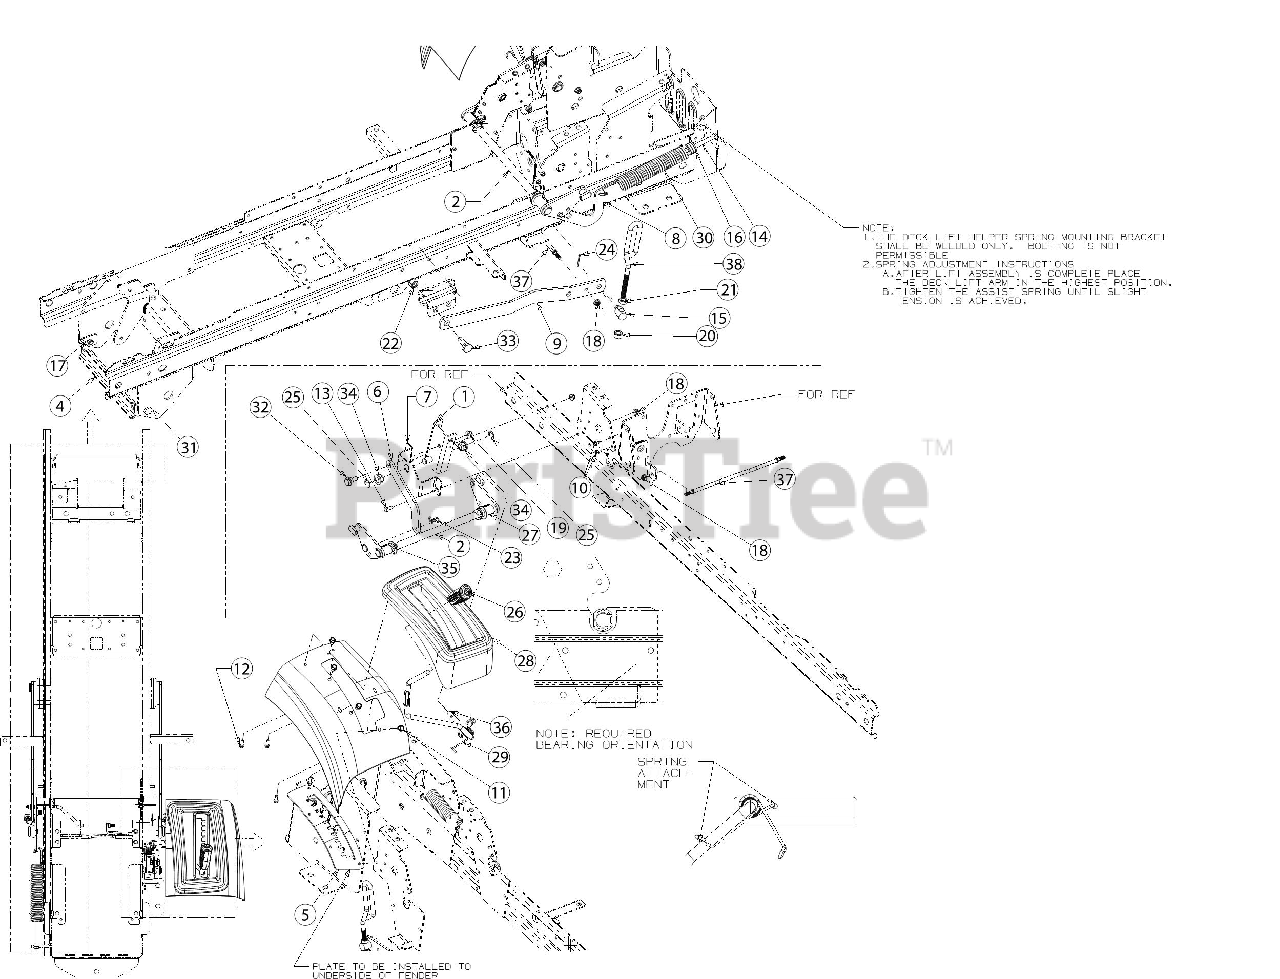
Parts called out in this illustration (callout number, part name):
1	MANUL LIFT LINK BRACKET
2	LIFT SHAFT ASSEMBLY MANUAL LIFT
4	FRONT HANGER BRACKET
5	HEIGHT INDEX BRACKET
6	MANUAL LIFT LINK
7	LIFT LEVER BRACKET
8	HELPER SPRING PLATE
10	SCREW 1/4-20 X.500
11	SCREW 5/16-18 x .625
12	SCREW 1/4-15 x .750
13	SCREW 5/16-18 x .75 GR5
14	SCREW 3/8-16X4.25 GR5
15	LIFT LINK FERRULE
16	SPRING INSERT
17	JAM LOCK NUT
18	FLANGE LOCK NUT 5/16-18
20	HEX NUT NYLOK 1/2-13
21	HEX NUT
22	HEX LOCK NUT NYLON
23	PIN:COTTER
24	COTTER PIN
27	SNAP SPACER .75
28	MANUL LIFT FENDER COVER
29	TORSION SPRING
30	EXTENSION SPRING
31	SHOULDER SCREW .500 DIA x .295
32	SHOULDER BOLT .562 x .360
33	SHOULDER BOLT
34	FLANGE BEARING
35	HEX FLANGE SPLIT BEARING
36	MANUAL LIFT HANDLE
37	DECK ANTI SWAY ROD
38	LIFT ADJUSTMENT LINK
